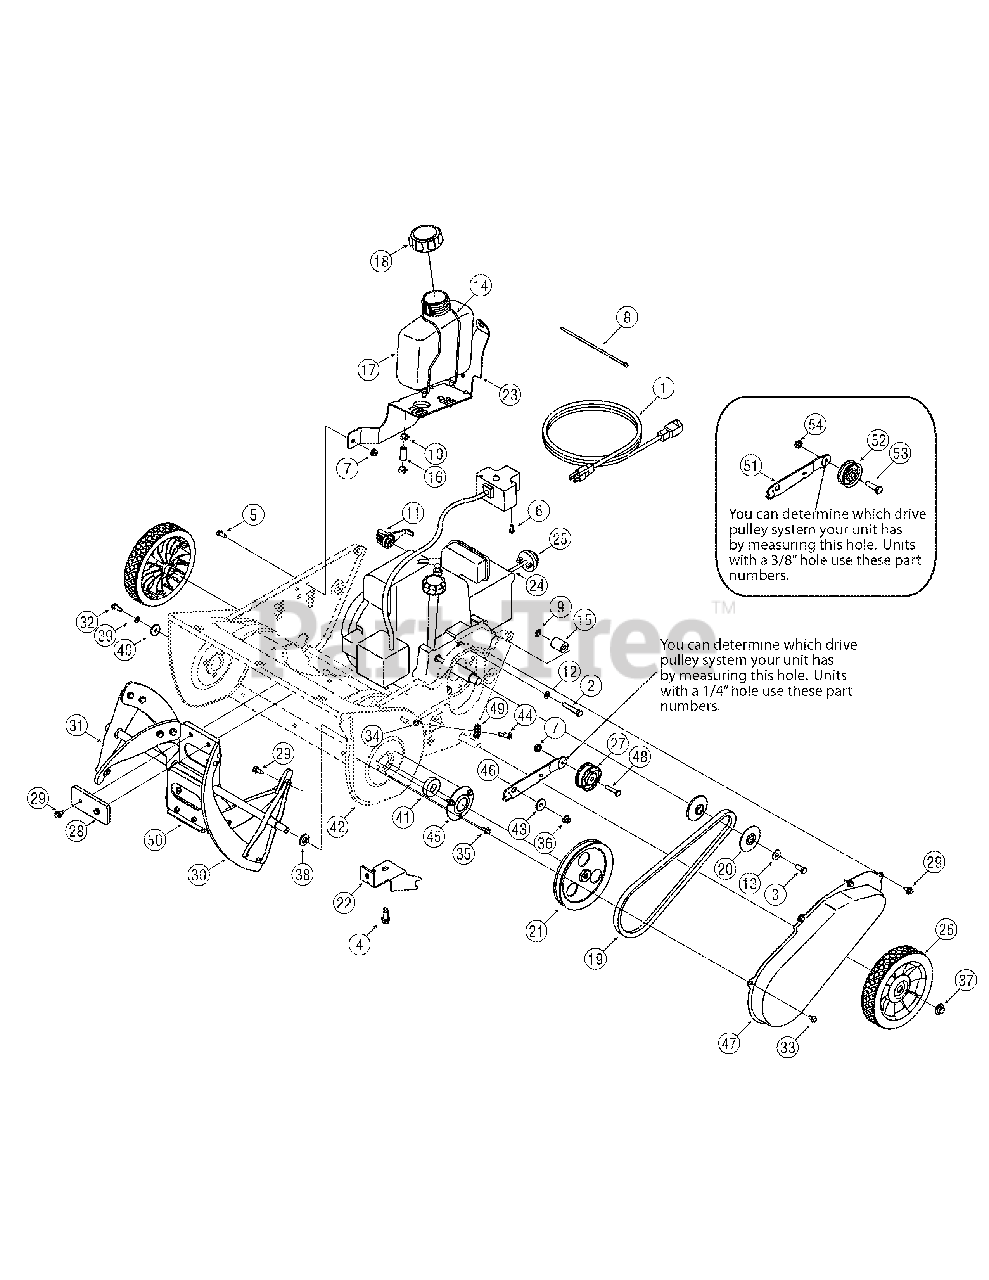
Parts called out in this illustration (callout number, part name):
1	Extension Cord
2	Hex Screw, 5/16-24 x 1.75
3	Hex Screw, 5/16-24 x .75
4	Self Tapping Screw, 3/8 -16 x1
5	Hex Screw, 1/4-20 x .62
6	Screw, #10-16 x .625
7	Hex Flange Lock Nut 1/4 -20
8	Push Mount Cable Tie
9	Speed Nut, .3125
10	Clamp, Hose
11	Knob, Choke
12	Washer, Lock 5/16
13	Flat Washer .349 x .879 x .063
14	Gas Tank Support Wire
15	Spacer, Engine
16	Hose, Fuel Line
17	Tank, Fuel
18	Cap, Fuel
19	V-Belt, 1/2
20	Pulley Half, .625 ID x 2.25 OD
21	Pulley, 1/2 V 1/2-20 LH x 6.0
25	Primer
26	Wheel, 7 x 1.5 Star Gray
27	Idler Pulley (Pulley hole 1/4")
28	Rubber Paddle
29	Hex Screw, 1/4-20 x .62
30	Crescent Spiral
32	Hex Screw 1/4-20 x .75 Gr. 5
33	Self-tapping Screw 1/4-20 x .375
34	Hex Lock Nut 1/4-28
35	Self-tapping Screw, 1/4-14 x .50"
36	Hex Flange Lock Nut, 5/16-18
37	Push Cap, 1/2"
38	Flat Washer .510 x 1.00 x .125
39	Lock Washer, 1/4
40	Flat Washer .265 x .938 x .120
41	Ball Bearing 17 x 40 x 12
43	Shoulder Spacer .25
44	Carriage Screw 1/4-28
48	Hex Screw, 3/8-24 x 1.25
49	Cable Roller
50	Auger Assembly
51	Idler Brkt. w/ Brake (Pulley hole 3/8")
52	Idler Pulley (3/8" hole)
53	Hex Screw 3/8-24 x 1.25
54	Jam Lock Nut 3/8--24
